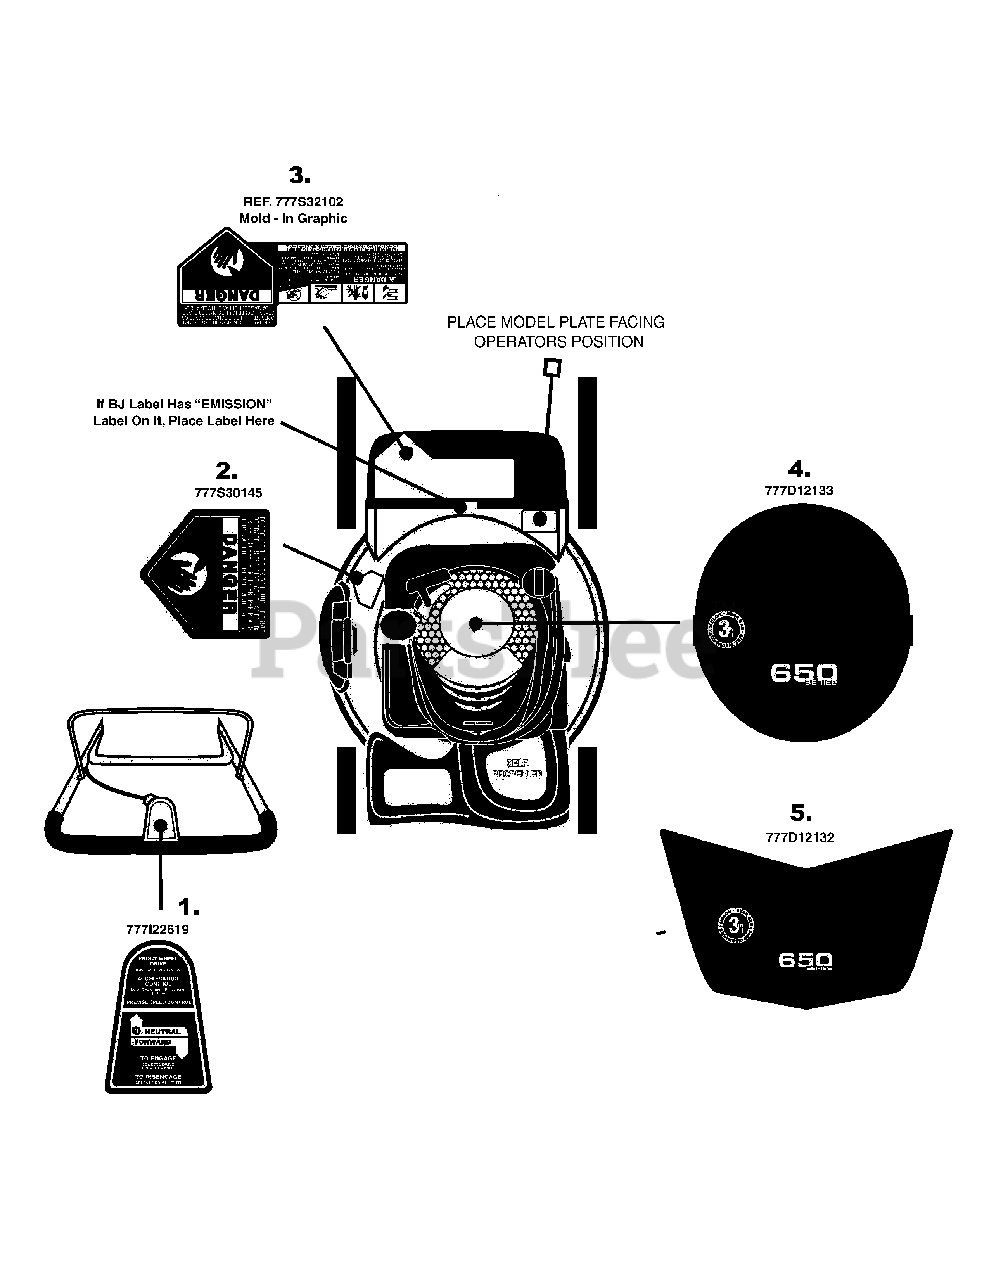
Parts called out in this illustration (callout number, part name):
1	LABEL-MOWER SQ LEVER
2	LABEL
3	LABEL
4	LABEL-MOWER SHROUD MTD GOLD 21"
5	LABEL-MOWER SHROUD MTD GOLD 21"
